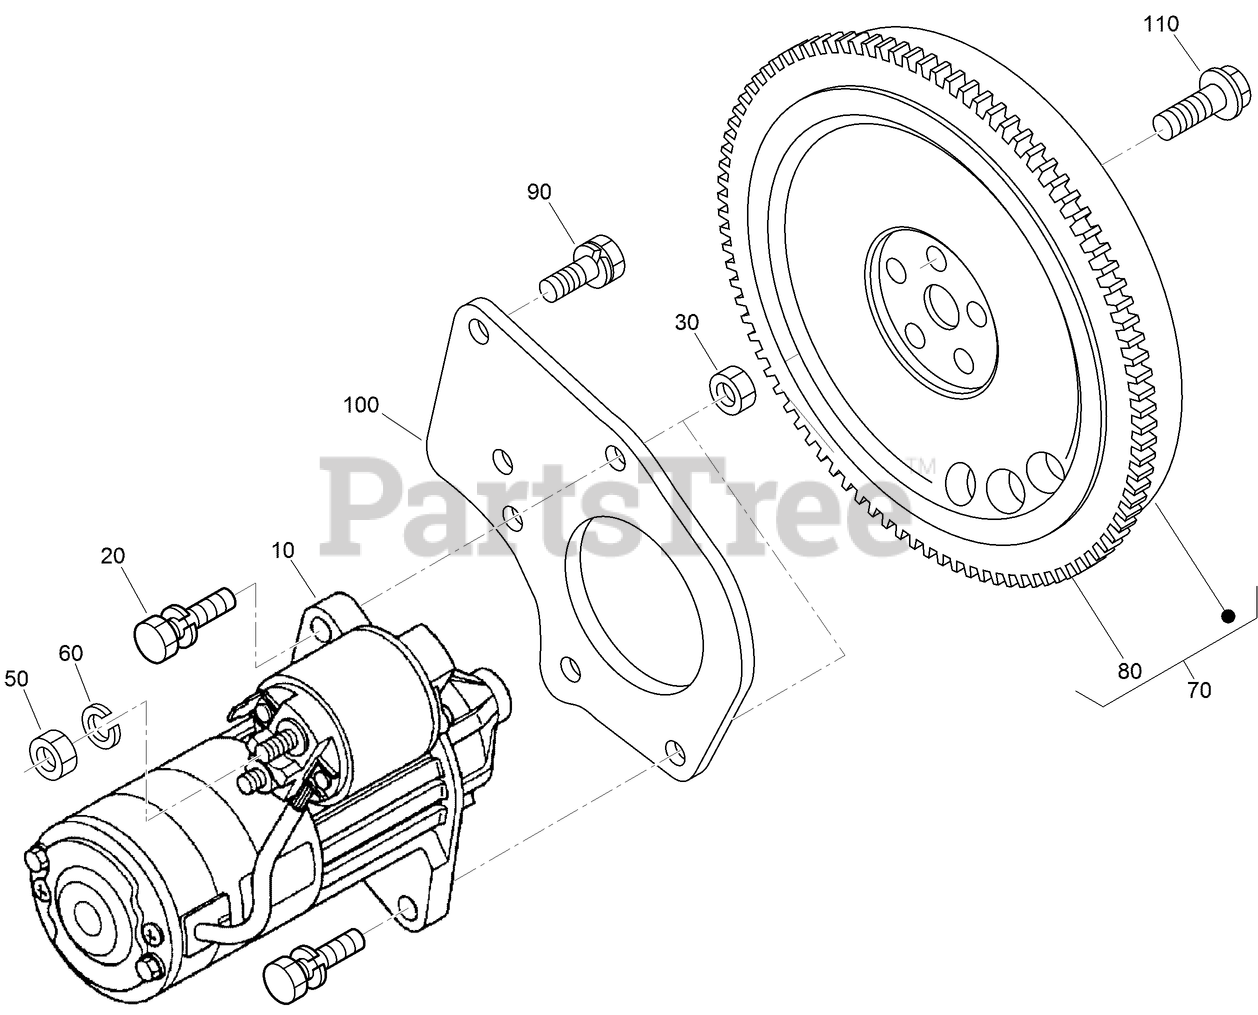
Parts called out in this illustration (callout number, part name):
60	WASHER-SPRING
70	FLYWHEEL ASM
80	GEAR-RING
90	BOLT-FLYWHEEL
100	PLATE-END, REAR
